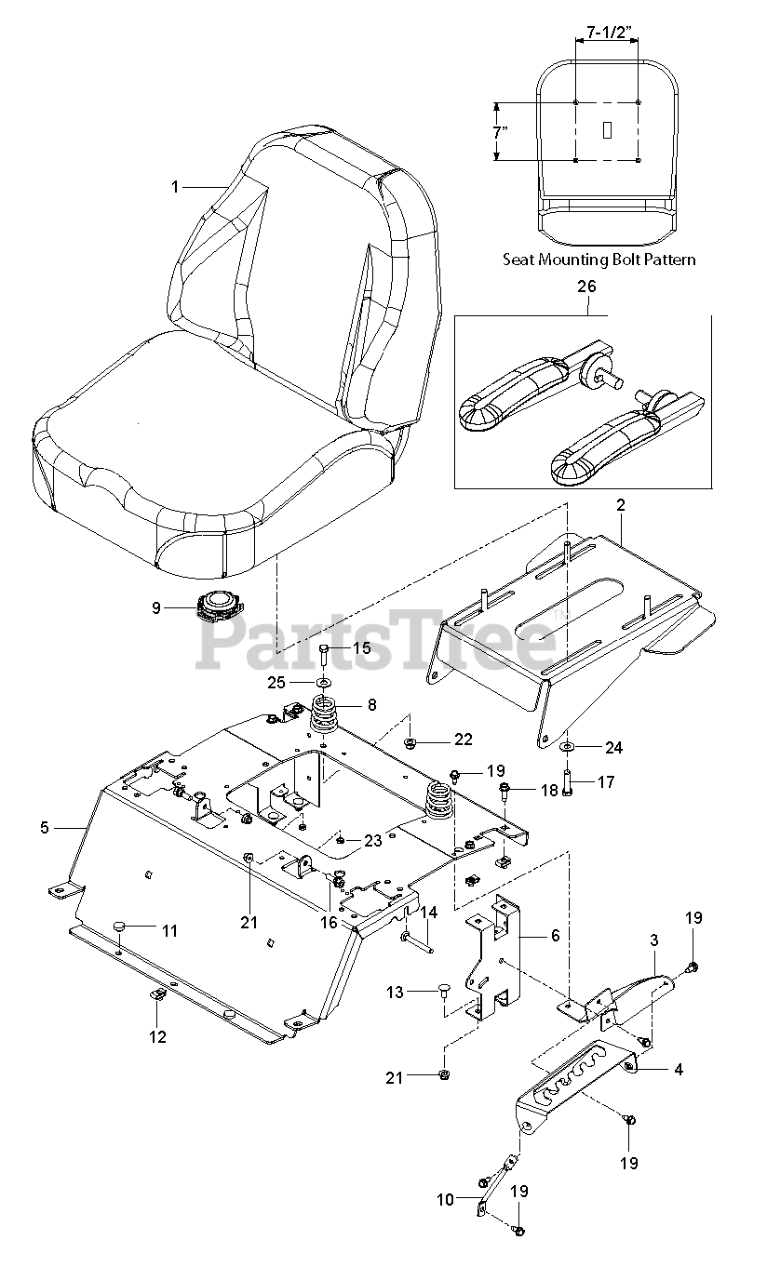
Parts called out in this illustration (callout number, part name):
1	SEAT. WOOD.BOTTOM.4-BOLT.HUSQ
2	PAN SEAT, 4-BOLT BLACK X428
3	PLATE.SUPPORT.DECK.LIFT.X431
4	PLATE.DECK.LIFT.X431
5	SUPPORT.SEAT.RZ.HUSQ.ORANGE
6	SUPPORT REAR SEAT BLACK
8	SPRING.COMPRESS.SEAT.TAPERED
9	SWITCH.SEAT.DELTA.OPC.
10	SUPPORT.LEG.DECK.LIFT
11	GROMMET.BUMPER
12	U-CLIP 5/16-18 NUT RETAINER
13	BOLT 5/16C X 3/4" CARRIAGE
14	RHSNB 5/16-18 X 2-1/2 GR5 ZD
15	BOLT
16	BOLT, SHOULDER
17	BOLT.5/16-18X1-1/4 FULL THD
18	SCREW.THDROL.5/16-18X3/4.TTY
19	BOLT.5/16HEX.WHS.HD
21	5/16-18 NYLOC FLANGE NUT
22	NUT 3/8-16 HEX FLG NYLOC ZD
23	NUT
24	WASHER
25	RP WASHER 3/8 FLAT
26	SEAT KING 18" WOOD BTM, ARM
